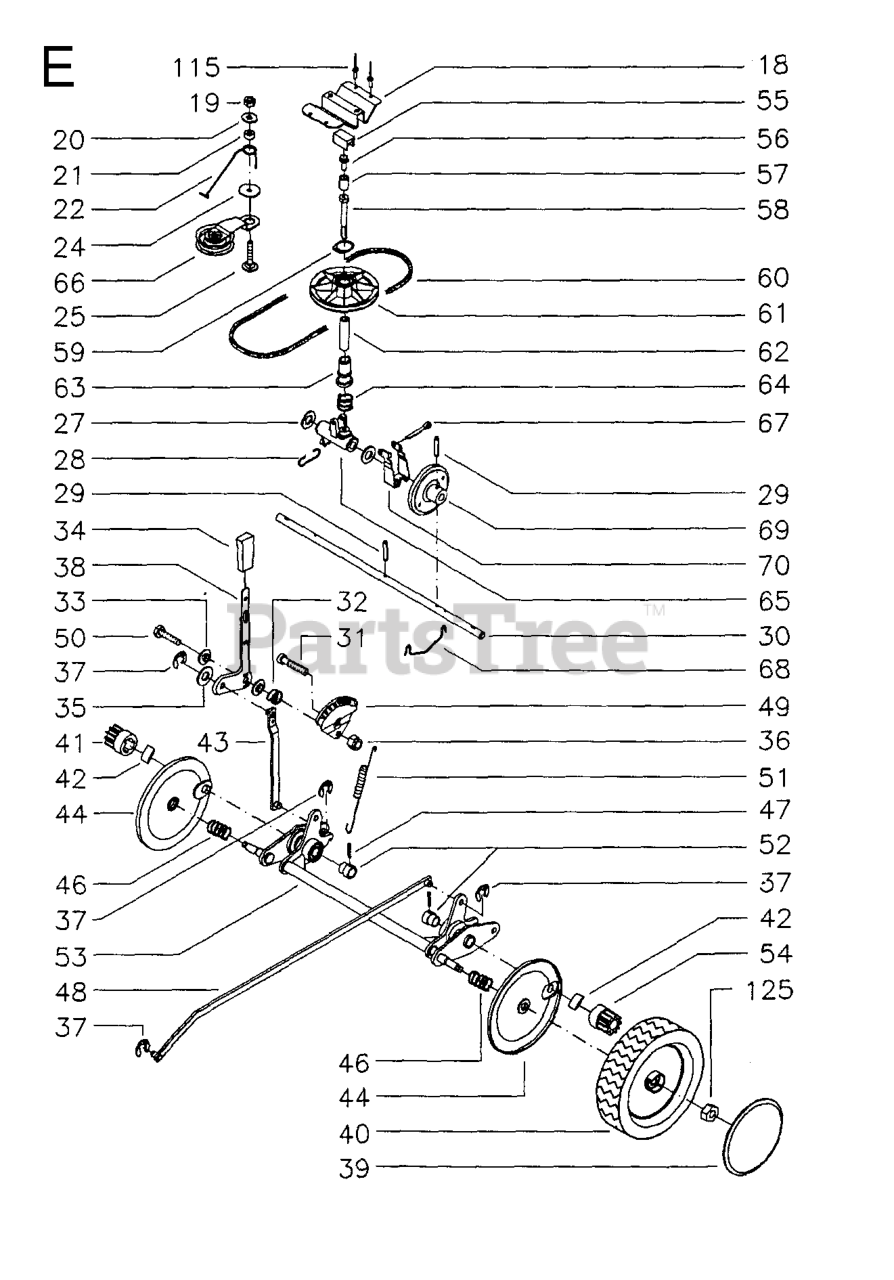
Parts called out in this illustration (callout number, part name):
19	LOCKNUT M6
27	WASHER
28	CLIPS
30	SHAFT
39	WHEEL COVER
41	PINION, RIGHT
42	CARRIER
44	SHIELD
46	SPRING
49	INDEXPLATE
54	PINION, LEFT
55	SLIDE BEARING
56	SCREW
60	BELT
61	PULLEY
63	SLEEVE
65	HOLDER
66	TENSIONER
68	HOLDER SPACER
69	WHEEL ASSY FRICTION
70	RAM
